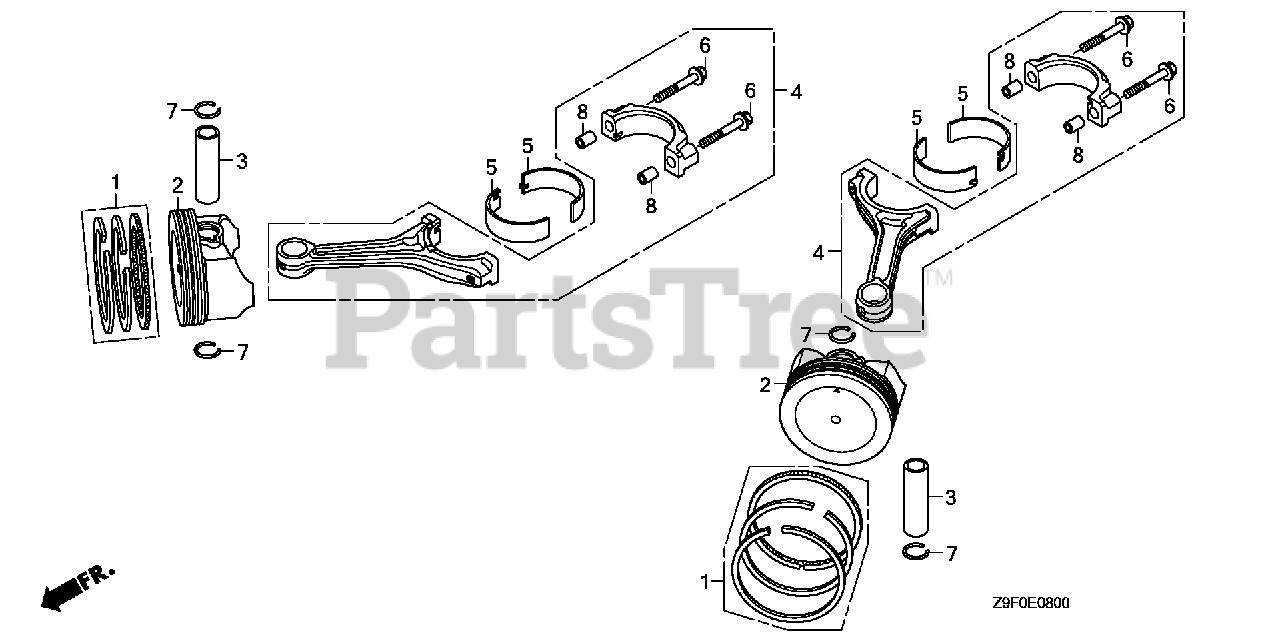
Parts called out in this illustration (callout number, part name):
1	RING SET, PISTON (STD) (TEIKOKU)
2	PISTON
3	PIN, PISTON
4	ROD ASSY., CONNECTING
5	BEARING A, CONNECTING ROD
6	BOLT, CONNECTING ROD (7X38)
7	CLIP, PISTON PIN (18MM)
8	PIN, DOWEL (9X10)
